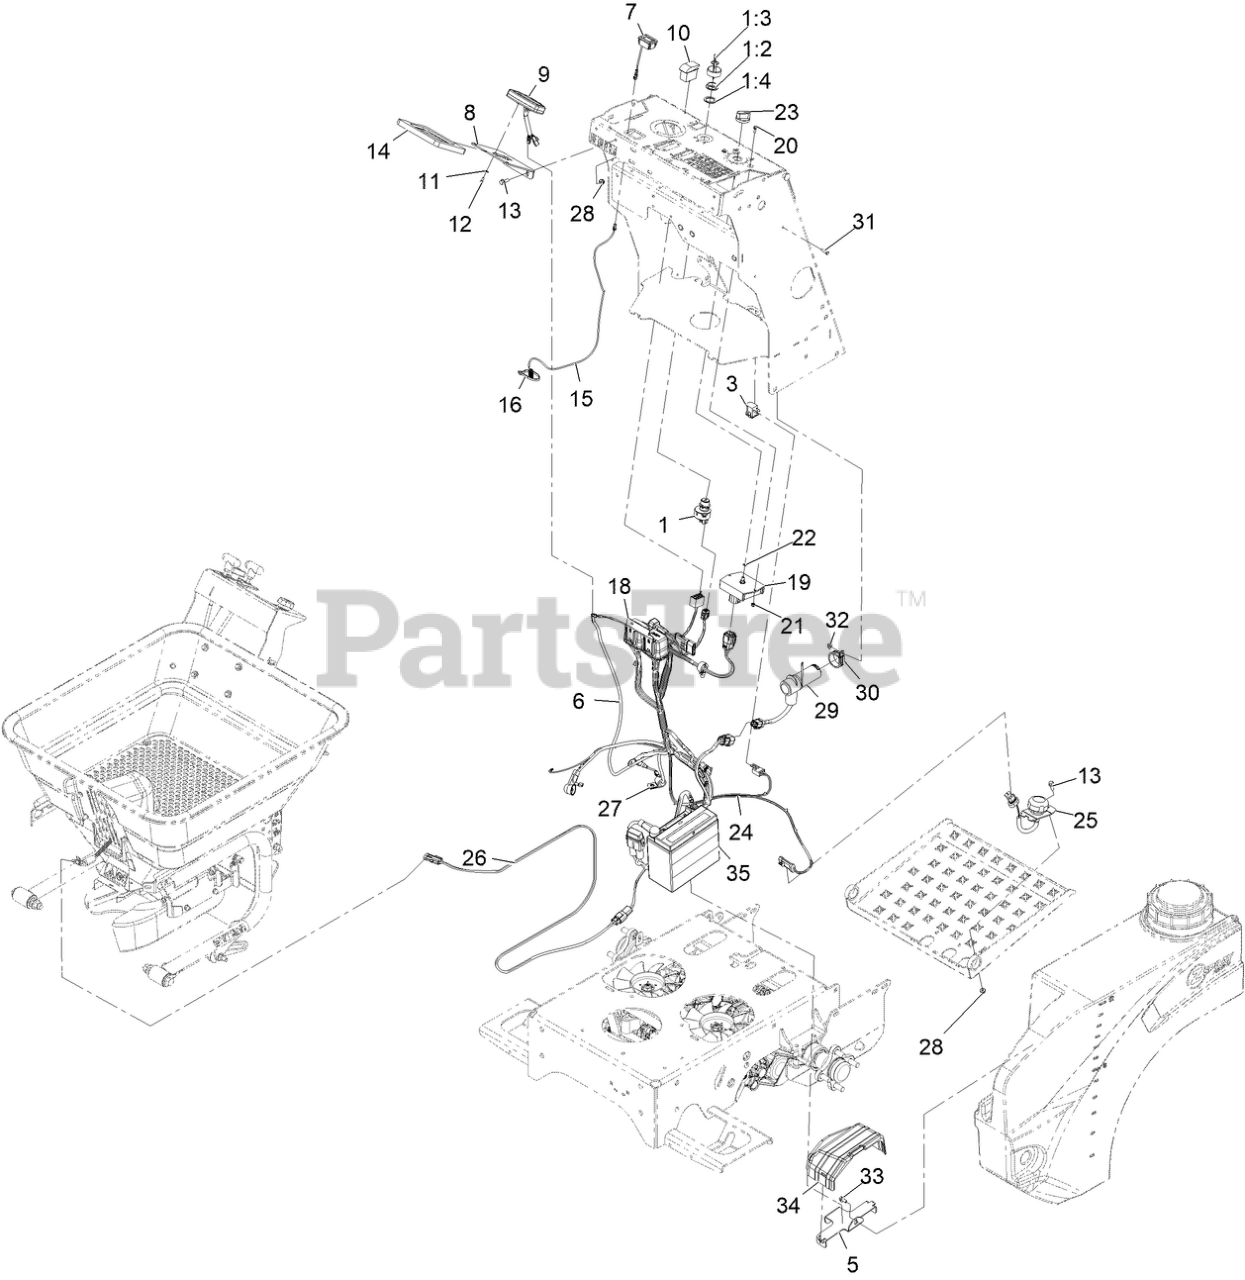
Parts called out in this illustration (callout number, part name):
1	IGNITION SWITCH ASM
1:2	NUT-MOUNTING
1:3	IGNITION KEY SET
1:4	WASHER-BACKUP
3	SWITCH-BAIL
5	STRAP-BATTERY
6	Cable-Trail Tech, Sensor
7	METER-TACH/HOUR
8	MOUNT-DISPLAY
9	HEAD ONLY, STRIKER
10	SWITCH-ROCKER
11	WASHER-FLAT
12	SCREW-HSH
13	Screw-HHF
14	PAD-DISPLAY MOUNT
15	WIRE-TACHOMETER
16	TIE-CABLE
18	BRACKET-COVER, FUSE
19	CONTROLLER-MOTOR, SPREADER
20	SCREW-HHF, SERRATED
21	NUT-HEX, NYLOCK
23	KNOB-INDICATING
24	HARNESS-JR36
25	Switch-Foot
26	HARNESS-SPREADER MOTOR
27	CLIP-LOOM
28	Nut-Hex Flange
29	HARNESS-CAPACITOR
30	CLAMP-R, CUSHION
31	SCREW-HH
32	Nut-Hex Flange
33	SCREW-HWH
34	COVER-BATTERY
35	BATTERY-AGM
